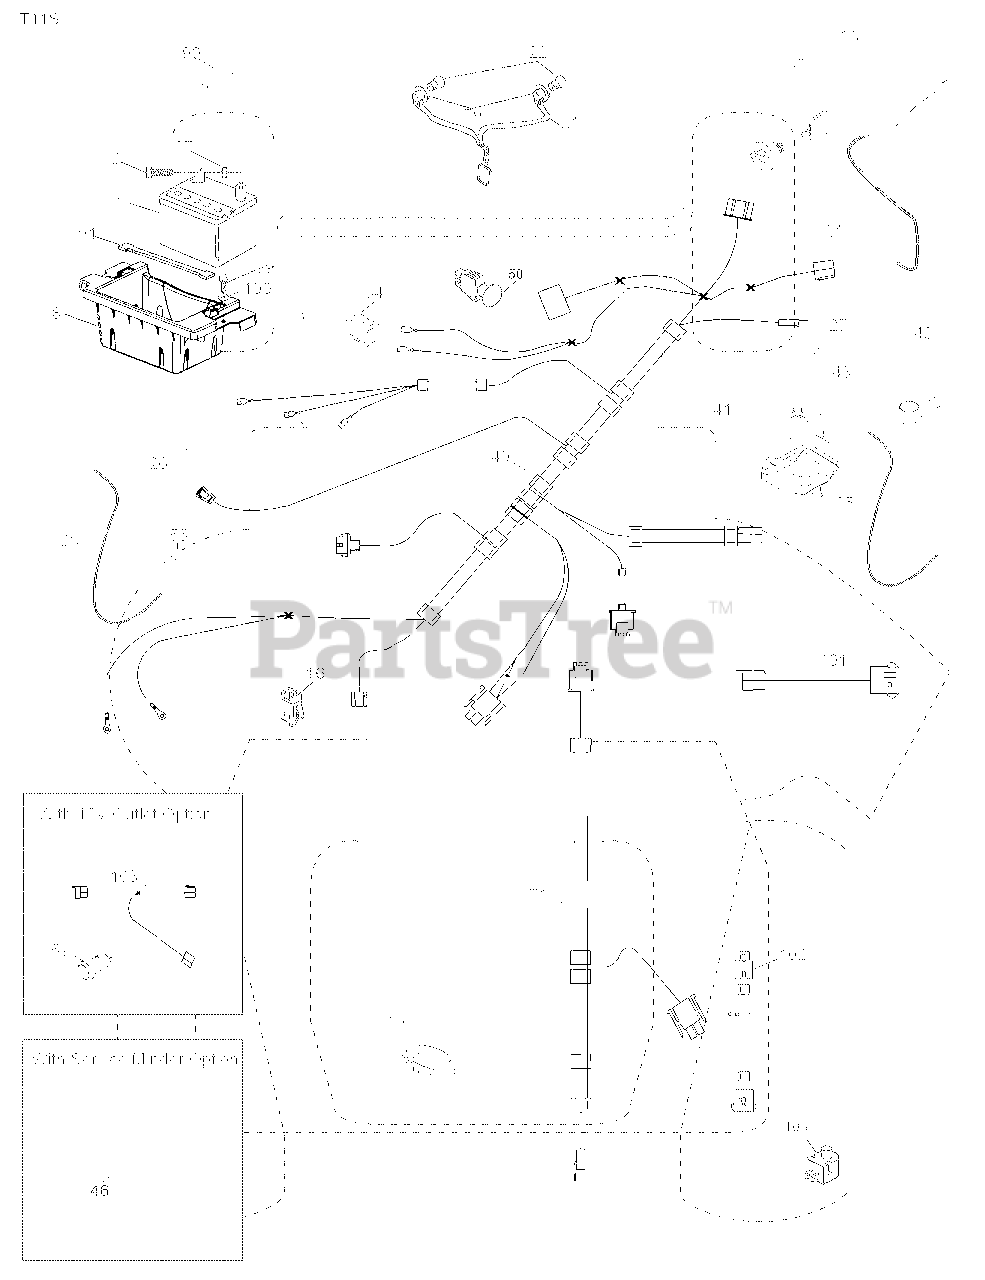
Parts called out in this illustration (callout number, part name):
1	Battery
2	Bolt Hex Hd 1/4-20 unc x 3/4
8	Battery Box
16	Switch Interlock
21	Harness Socket Light
22	Bulb, Light #1156
24	Cable Battery
25	Cable Starter
27	Nut Keps Hex 1/4-20 unc
28	Cable Ground 21" Blk 6 Ga.
29	Switch Seat
30	Switch Ign
34	Switch Light/Reset
40	Harness Ign. Dash
41	Screw Thd Cut 1/4-20 x 1/2
42	Cover Terminal Red
43	Solenoid
46	Gauge Hourmeter
50	Switch PTO
55	Screw Thdrol 5/16-18 x 3/4
59	Outlet 12-Volt
71	Harness Chassis
79	Socket Asm Bulb
90	Cover Terminal Battery
91	Strap Battery
99	Screw Hexwsh Thdrol 1/4-20 x 3/4
100	Washer 9/32 x 7/8 x 16 Ga.
101	Pigtail Malnlk
102	Harness Pigtail
103	Harness Pigtail
105	Switch Reverse
